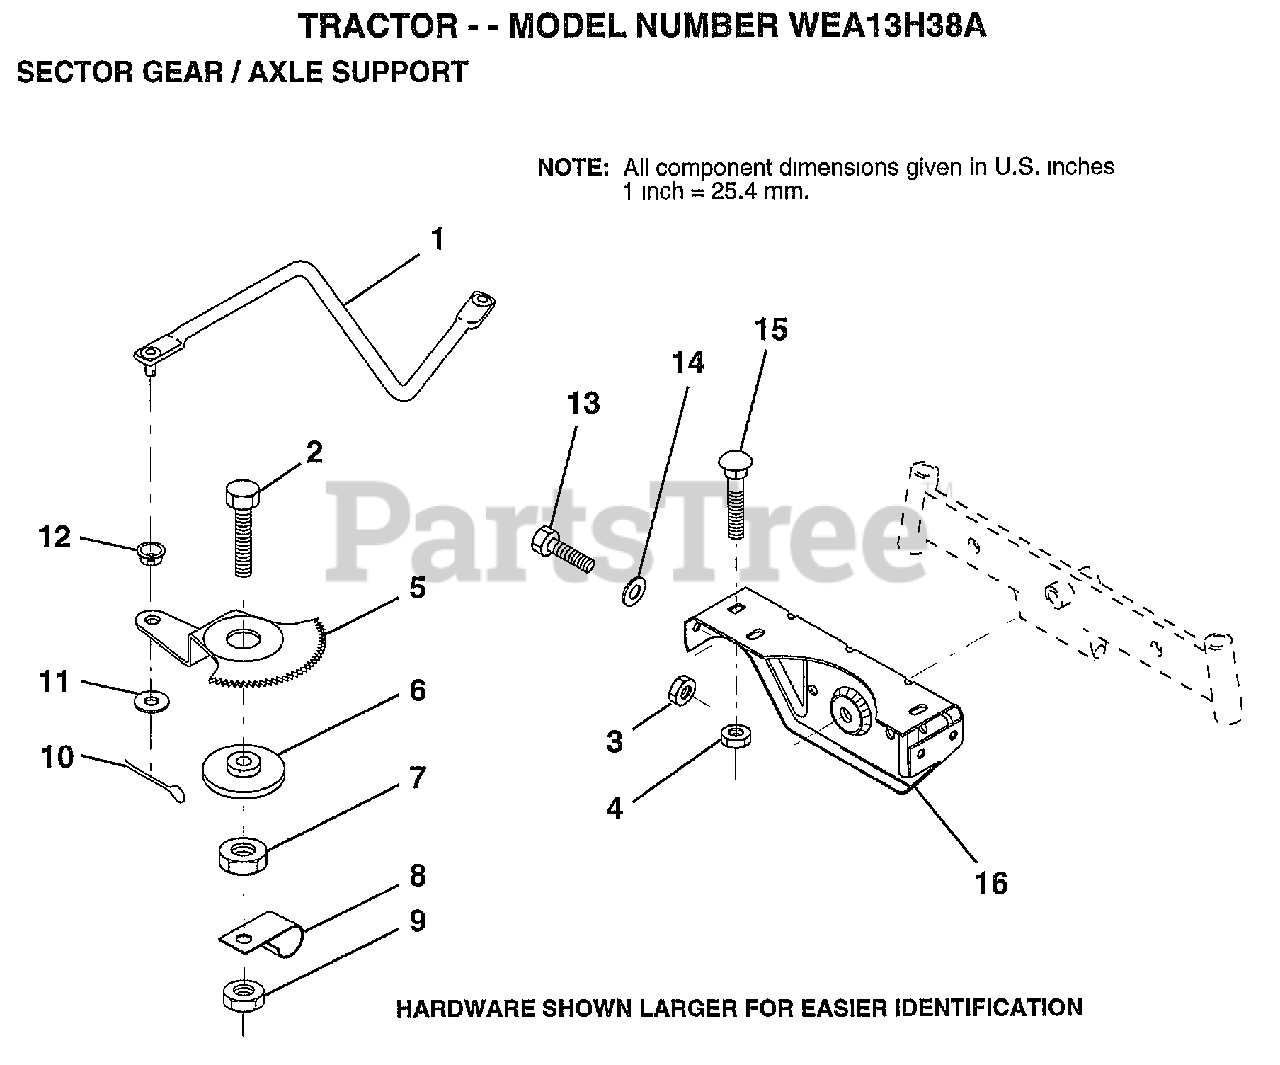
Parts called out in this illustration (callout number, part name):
1	DRAG LINK
2	"BOLT,HEX"
5	GEAR SECTOR
6	BUSHING
7	NUT
8	CLIP INSULATOR
9	NUT LTV
10	COTTER PIN
11	WASHER
12	BUSHING.DRAGLINK
13	BOLT
14	WASHER
15	BOLT
16	SUPT AXLE FRONT
